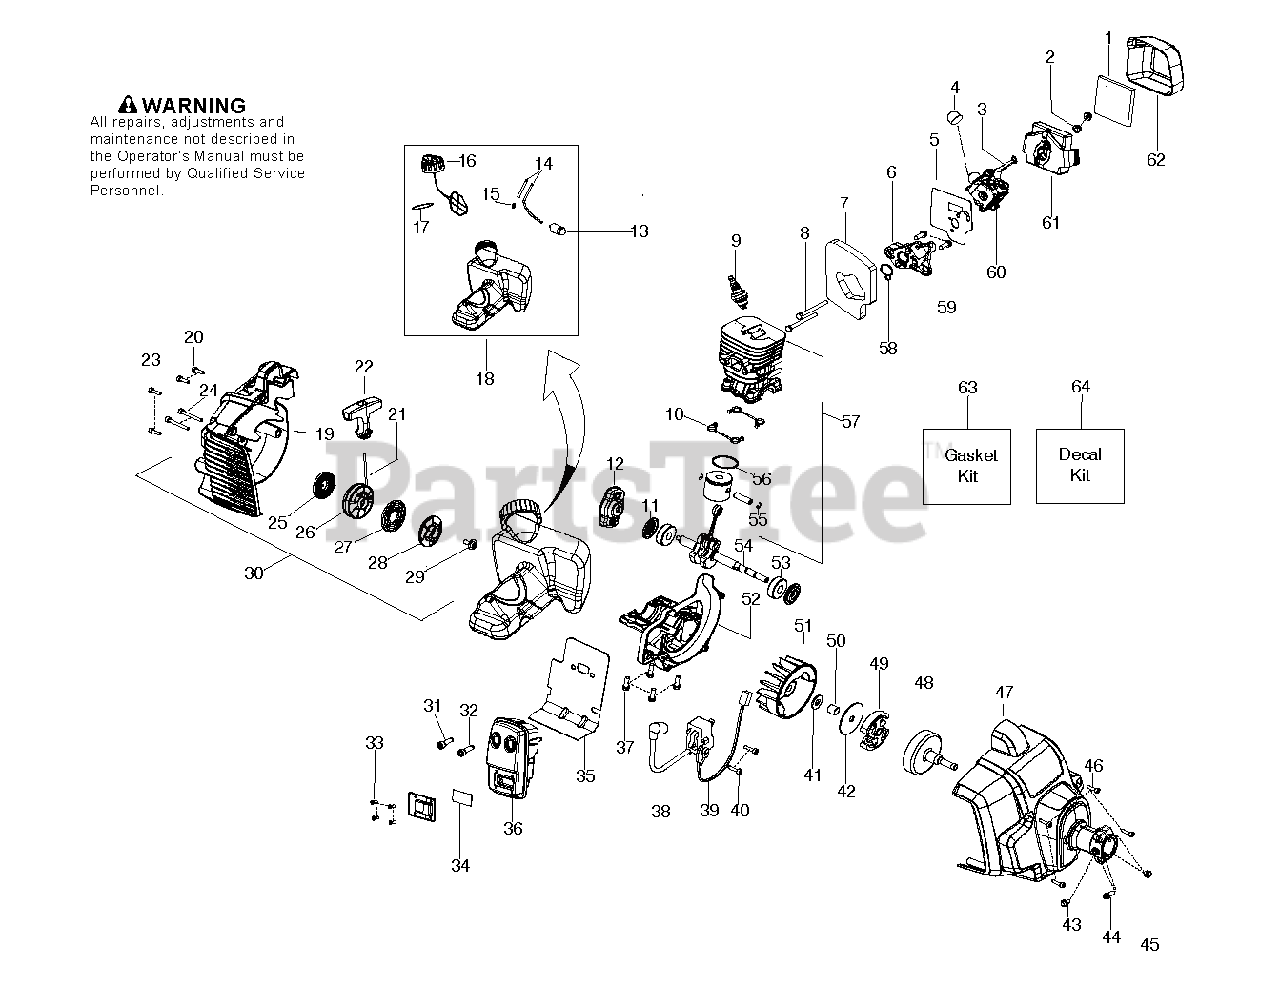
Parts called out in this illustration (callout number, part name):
1	Air Filter, Foam
3	Choke Lever
4	PURGE BULB ZAMA
5	Carburetor Gasket Kit, 28cc
6	CARB ADAPTOR
7	Gasket Kit, 28cc
8	BOLT CARB ADAPTOR
9	PLUG-SPARK (RCJ-8Y)
10	SEAL CYLINDER
11	Gasket Kit, 28cc
12	Starter Pawl Bridge
13	FUEL PICK-UP ASSY
14	KIT-LINE(FUEL)
15	Fuel Line Fitting, Double Barb
16	Fuel Cap Assembly
17	Gasket Kit, 28cc
18	KIT FUEL TANK PP 28CC
19	Starter Housing
21	KIT ROPE
22	STARTER HANDLE
24	SCREW M5-0.8X30MM
25	KIT STARTER SPRING
27	DRIVER SPRING
28	PULLEY STARTER DRIVE
30	Starter Housing Kit
31	BOLT MUFFLER
32	BOLT MUFFLER
33	SCREW-6-19X5/16PLAST PA
34	Spark Arrestor Screen Kit
35	Gasket Kit, 28cc
36	KIT MUFFLER W/CATALYST
37	SCREW-M5-0.8 X 25MM(TAP)
38	IGNITION MODULE MBU-7
39	ASSY MOD LEADWIRE
40	SCREW M4 X .70 TT 16MM
41	WASHER CLUTCH
42	WASHER-CLUTCH
43	SCREW-10-14 X 1/2 PLASTITE
44	SCREW-10-24 X 1" (UNC)
45	LOCKNUT-HEX 10-24
46	SCREW M4 X .70 TT 16MM
47	Fan Housing Assembly
48	Clutch Drum Assembly
49	Clutch Assembly
50	SPACER FLYWHEEL
51	FLYWHEEL
53	Radial Ball Bearing, 6201
54	ASSY CRANKSHAFT
55	WRIST PIN RET.
56	RING PISTON 28CC AIP
57	Piston and Cylinder Kit
58	Gasket Kit, 28cc
59	SCREW-M5-0.8 X 25MM(TAP)
60	Carburetor Assembly
61	Air Filter Housing, Black
62	Filter Housing Cover
63	Gasket Kit, 28cc
64	KIT DECAL
